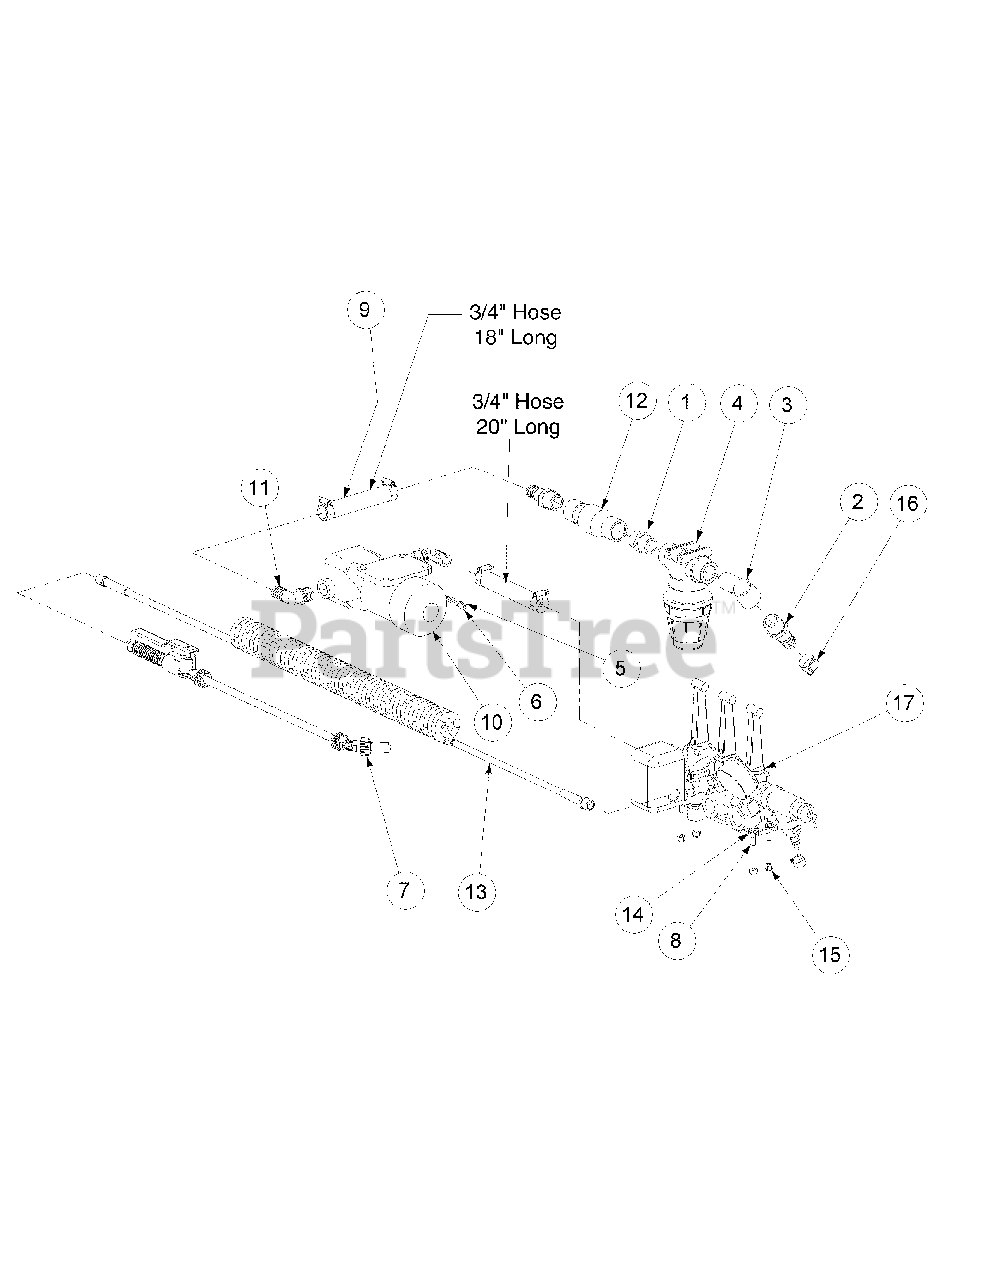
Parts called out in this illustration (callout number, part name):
1	Nipple, 3/4 NPT
2	Male Insert, 3/4
3	Street Elbow, 3/4 NPT
4	Strainer, 3/4 PVC Line
5	Connector, Snap Plug, Male
6	Connector, Snap Plug, Female
7	Trigger Jet Spray Gun
8	HHCS, 1/4-20 x 1.00, SS
9	Hose, 3/4
10	Electric Pump, 4.8GPM 12V
11	Hose Barb, 3/4 90 degree Elbow
12	Spring Loaded Check Valve
13	Hose Assembly, 25 ft.
14	Flat Washer, 1/4"
15	Nylock Nut, 1/4-20
16	Hose Clamp, 1/2, 7/8
17	Control Valve Manifold Assembly
17	Switch - Pressure Control
18	Harness Assembly, Kawasaki
